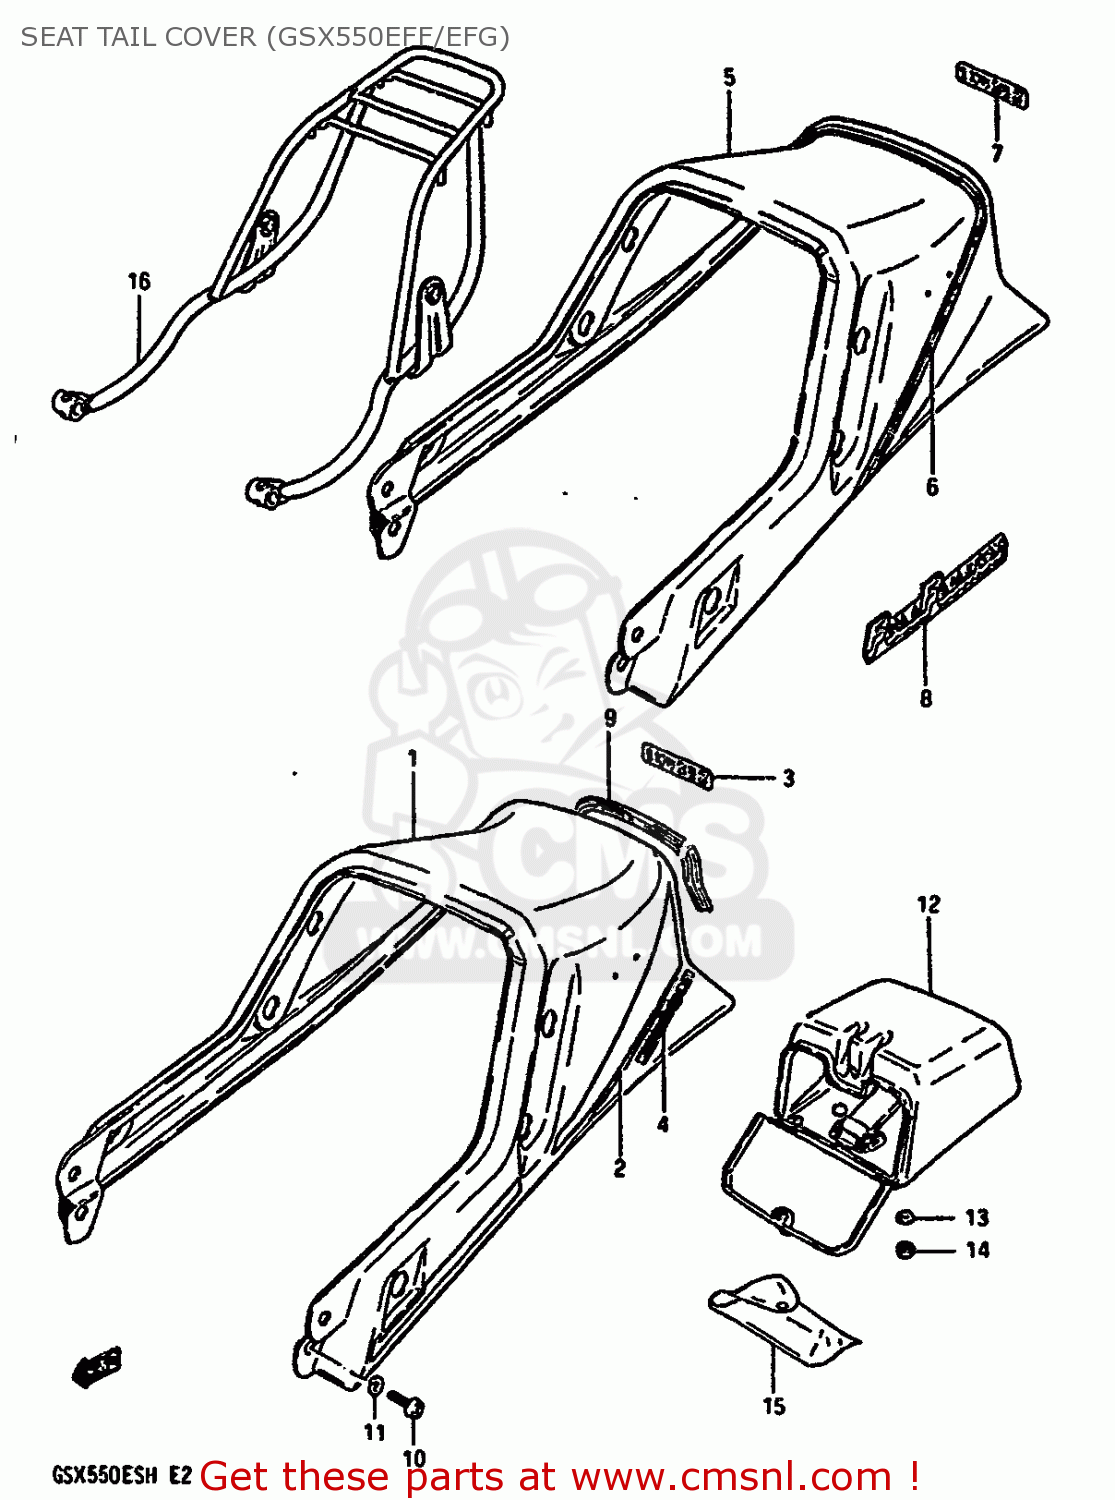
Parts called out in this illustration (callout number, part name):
1	COVER,SEAT TAIL
2	TAPE SET,TAIL COVER (BLACK)
3	EMBLEM
4	EMBLEM
5	COVER,SEAT TAIL
6	TAPE SET,TAIL COVER
7	EMBLEM
8	EMBLEM
9	BLIND,SEAT TAIL COVER
10	SCREW
11	WASHER,LOCK
12	BOX,SEAT TAIL
13	WASHER
14	NUT
15	TOOL ASSY
16	CARRIER, SPORTS
